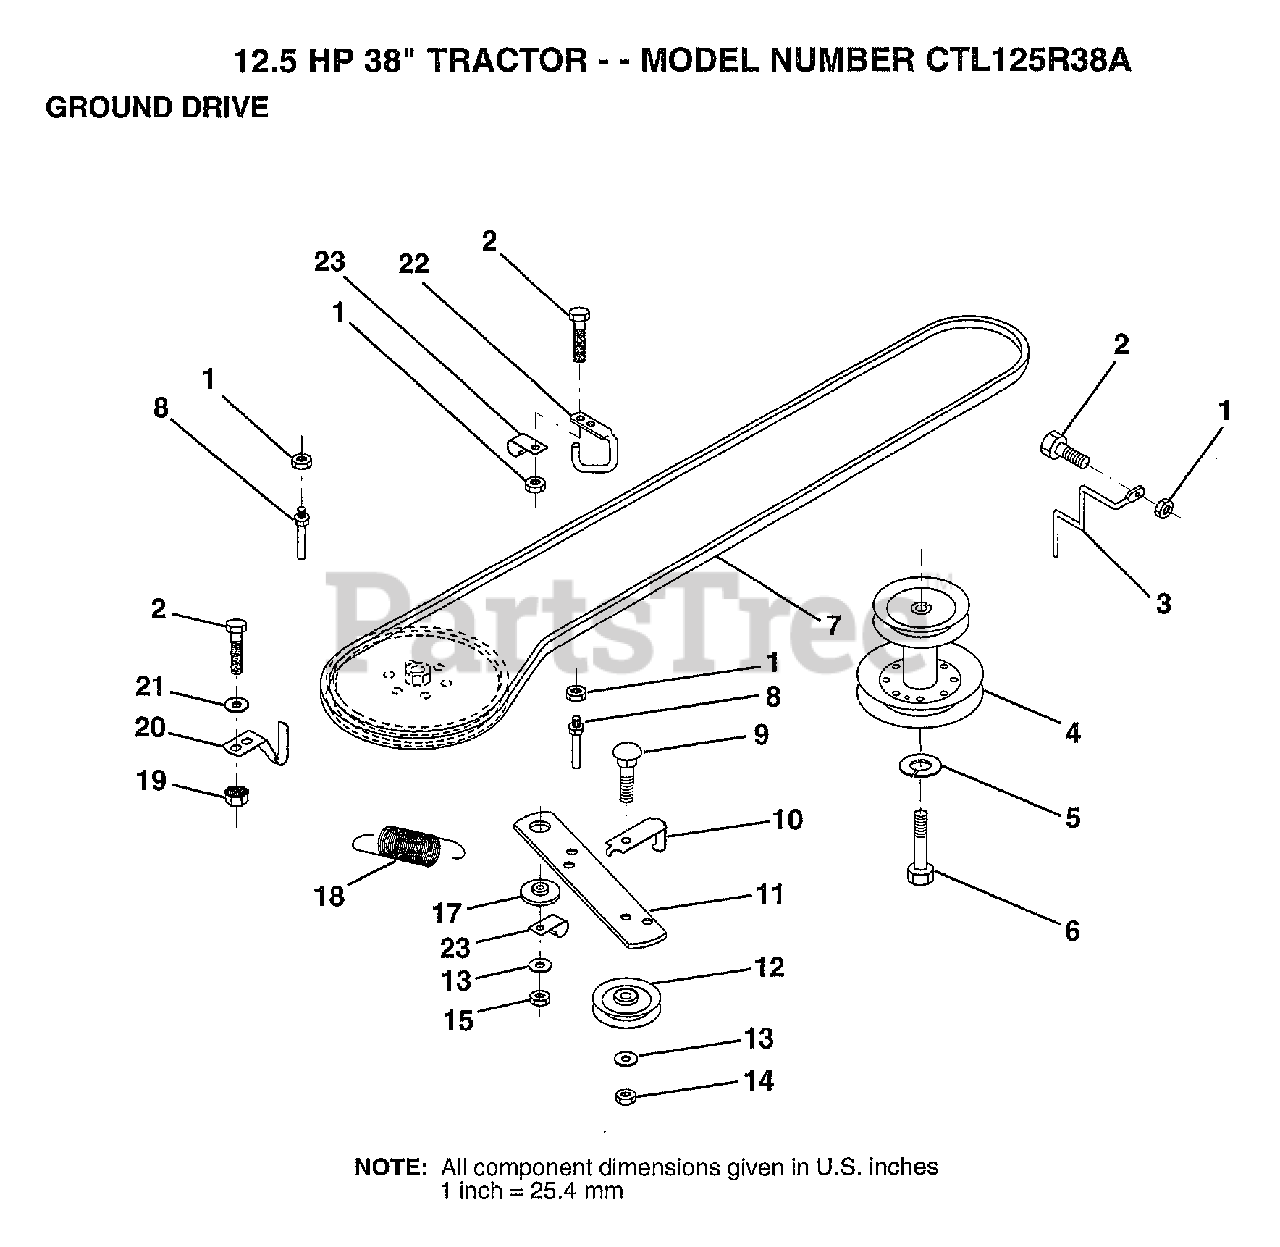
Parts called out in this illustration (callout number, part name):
2	BOLT
3	KEEPER MWR DR BLT
4	PULLEY.ENGINE.LR
5	LOCKWASHER
6	HEX BOLT
7	BELT
8	"KEEPER,DRIVE BELT"
9	BOLT
10	"KEEP,IDLER DR BEL"
12	PULLEY.IDLER.FLAT
13	WASHER
14	LOCKNUT
17	SPACER RETAINER
20	KEEPER.BELT.T/A
21	WASHER
22	"KEEPER,FRA DR BEL"
23	CLIP INSULATOR
